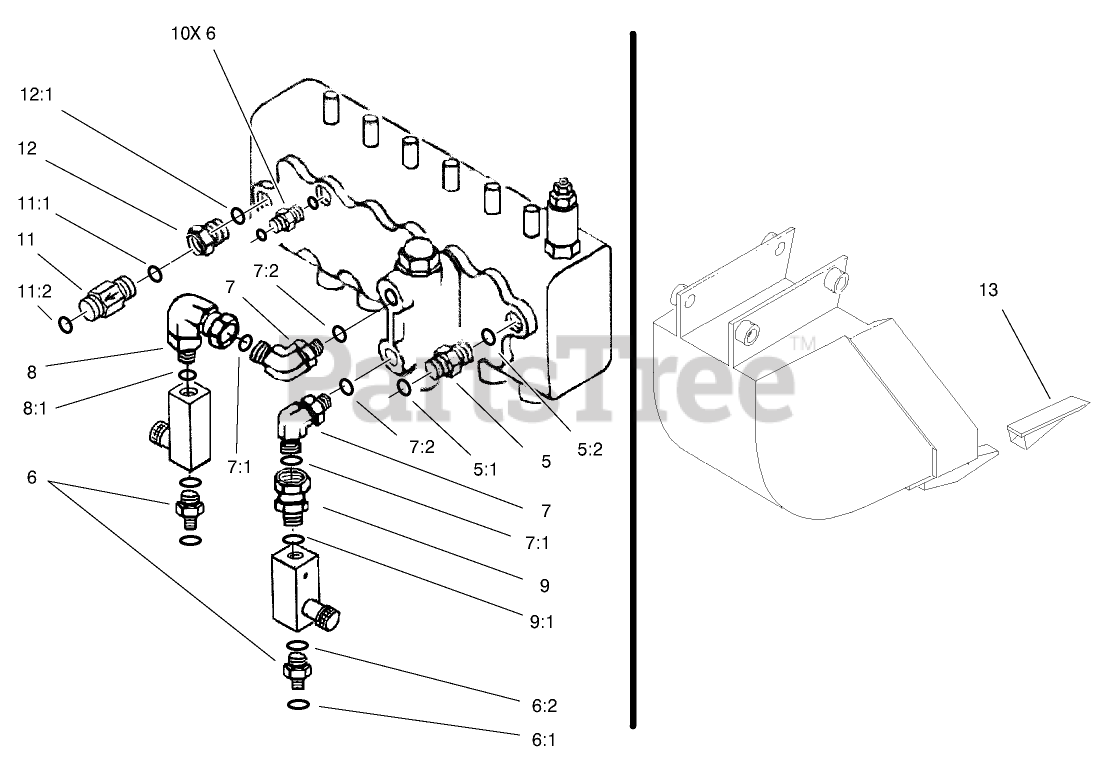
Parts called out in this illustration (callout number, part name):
5	FITTING-STRAIGHT
5:1	O-RING
5:2	O-RING
6	FITTING-STRAIGHT
6:1	O-Ring
6:2	O-RING
7	FITTING-ELBOW, 90 DEG
7:1	O-RING
7:2	O-RING
8	FITTING-SWIVEL, 90 DEG
8:1	O-RING
9	FITTING-SWIVEL, STRAIGHT
9:1	O-RING
11	CHECK VALVE
11:1	O-RING
11:2	O-RING
12	REDUCER-ADAPTER
12:1	O-RING
13	TOOTH-BUCKET
